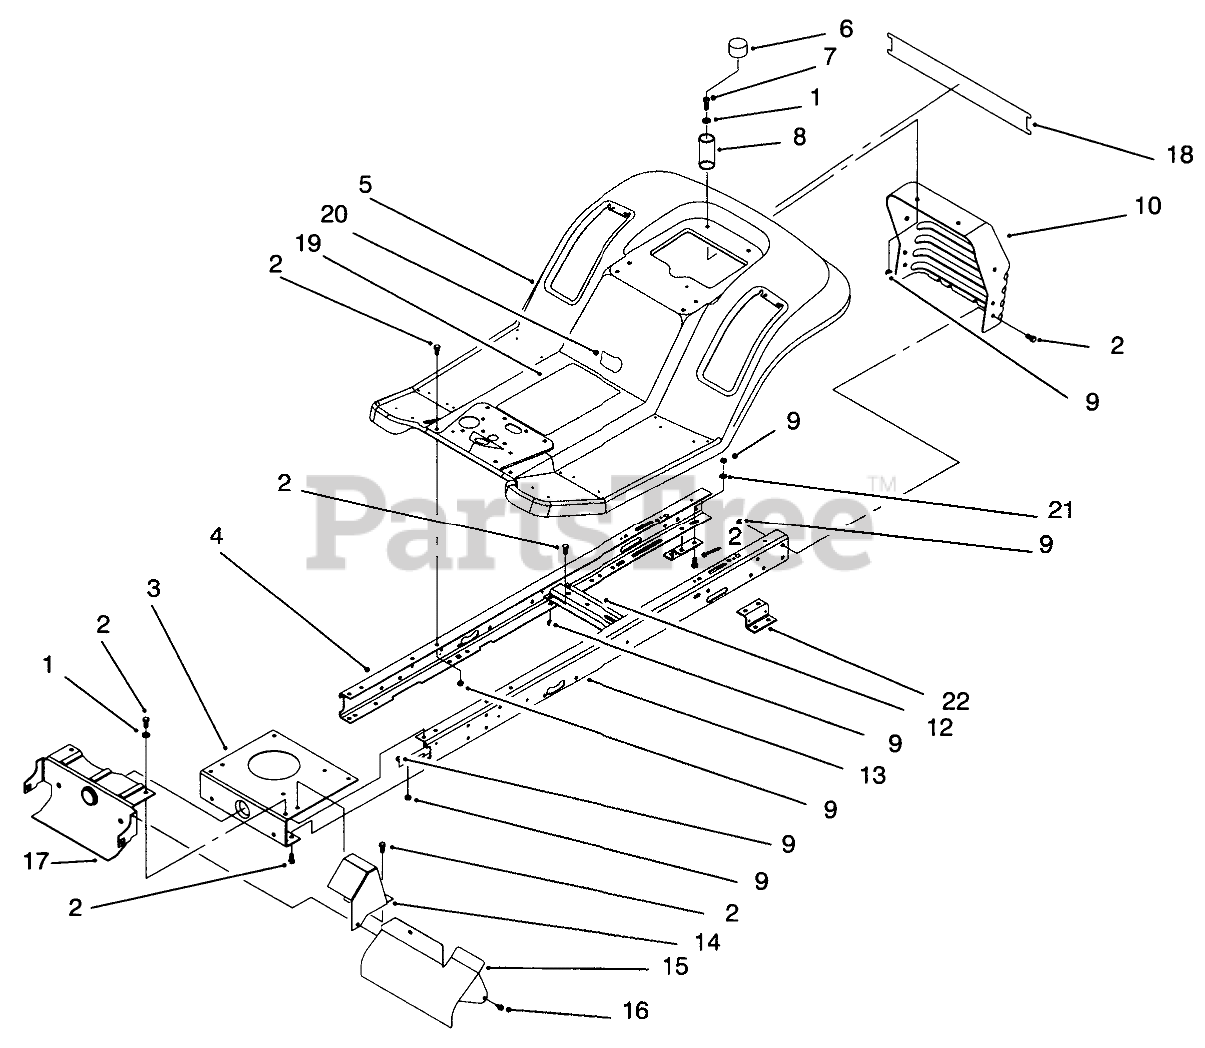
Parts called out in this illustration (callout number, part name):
1	WASHER-PLAIN
2	SCREW-HH
3	Plate-Engine Mount
4	Frame-Rail R.H.
5	BODY-REAR
6	CAP-PROTECTOR
7	SCREW-HH
8	SPRING-COMPRESSION
9	NUT-LOCK, NI
10	Panel-Rear Hitch
12	Bracket-Idle Pivot
13	Frame-Rail L.H.
14	Shield-Exhaust Pipe
15	Shield-Muffler
16	SCREW-HWHTF
17	Support-FrontAxle
18	DECAL - REAR BODY
19	DECAL - INSTRUCTION
20	DECAL - USA
21	WASHER-PLAIN
22	Bracket-Trans. Mount
